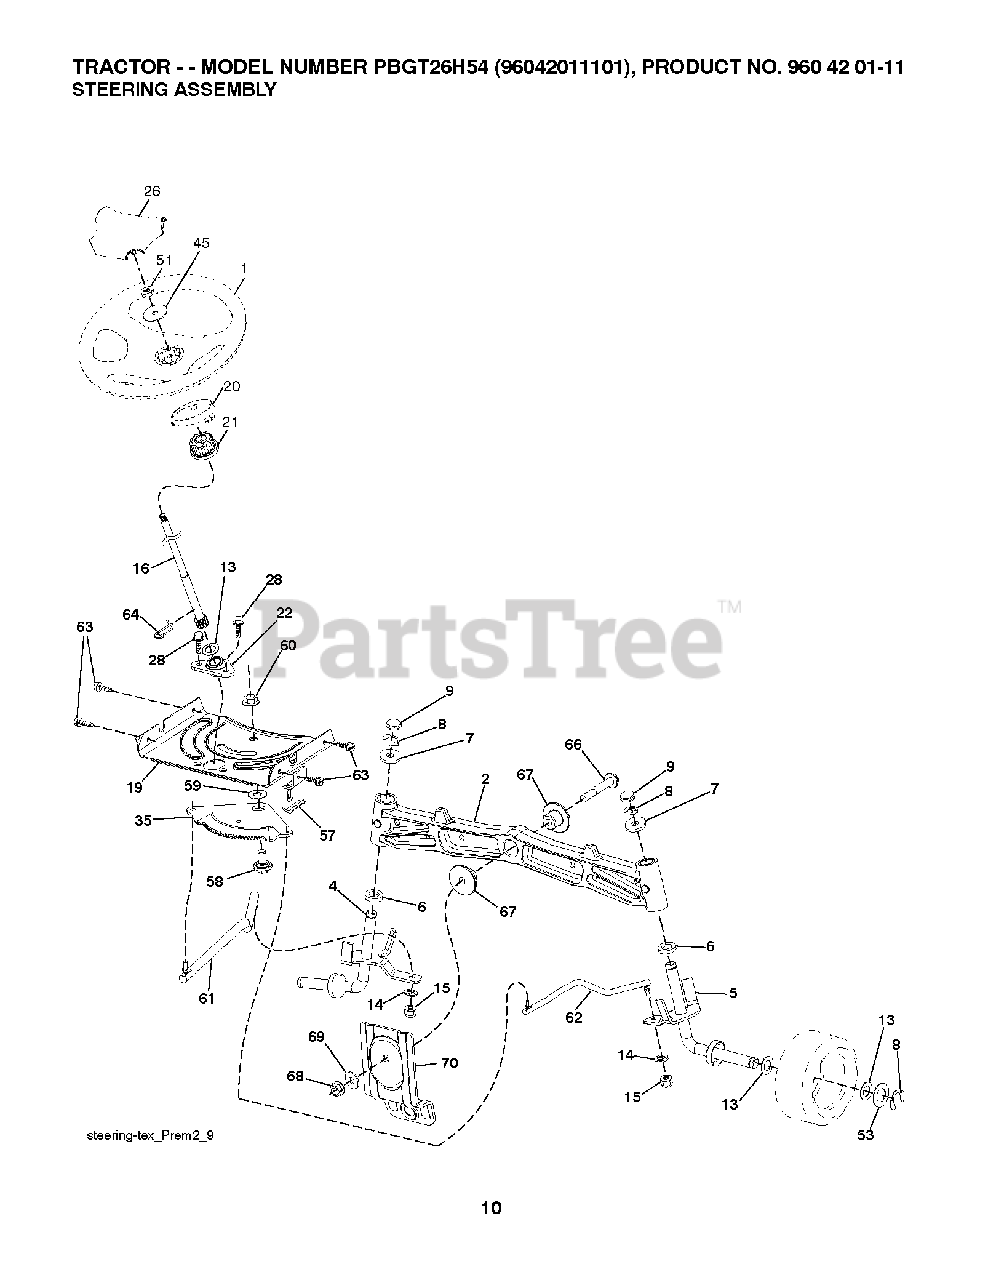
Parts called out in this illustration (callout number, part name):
1	WHEEL.STEERING.MLT.BR.YEL/OVRM
2	AXLE.CAST.IRON
4	SPINDLE.WELDED.LH.16"TEX
5	SPINDLE.WELDED.RH.16"TEX
8	RING CLIP
9	CAP.SPINDLE.BLACK
14	WASHER, LOCK 3/8
15	NUT CROWNLOCK 3/8-24
16	SHAFT, STEERING
19	PLATE.STEER.DDL.NLT/NG
20	BOOT, STEERING
21	ADAPTER, WHEEL STNG..
22	STEERING.SUPT.LOWER.
26	CAP.WHL.STRNG.MULTI.BRND.YEL
28	SCREW, 3/8-16X3/4
35	GEAR.SECTOR.PLATE.DDL.
45	WASHER 9/16"ID, 2 3/8""OD
51	NUT.HEX.1/2-20
53	WASHER.HARDENED
57	BRKT.UPSTOP.GT/LT.TEX
58	BOLT.SHOULDER.SECTOR.P
59	WASHER.THURST.SECTOR.S
60	NUT FLANGE LOCK 5/8-11
61	DRAGLINK.LH.BALLSTUD.D
62	DRAGLINK.RH.BALLSTUD.D
63	SCREW
64	RETAINER.CLIP.SPRING.S
66	BOLT HEX FGHD 7/16-14 X 3 SERR
67	BUSHING.PM.FRONT AXLE
68	NUT.LOCK.FLANGE.7/16
69	WASHER.1.5X.505X.118
70	BRKT.DECK.SUSPENSION.F
